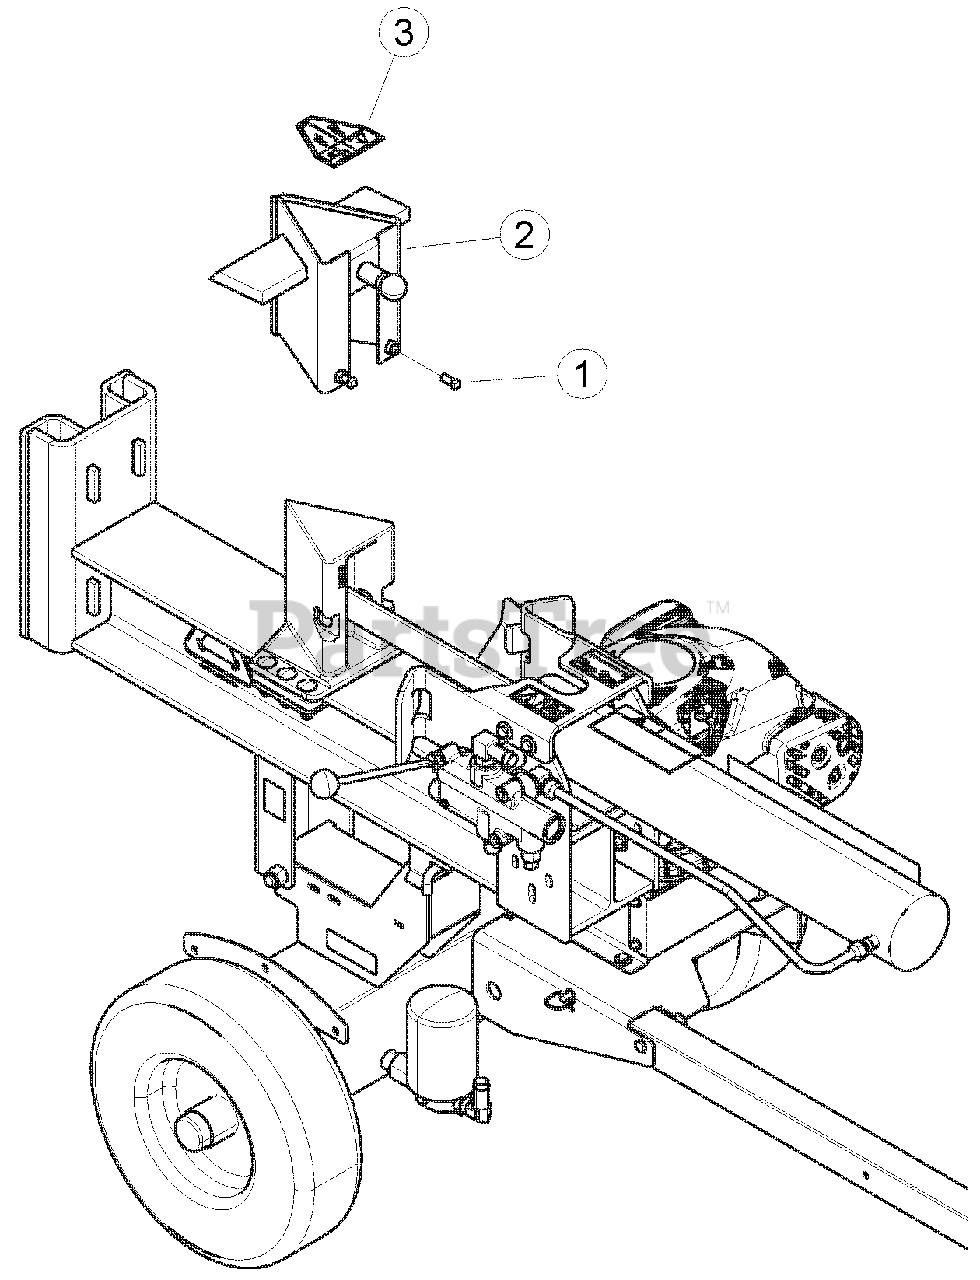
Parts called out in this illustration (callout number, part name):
1	SCREW, 3/8 X 3/4 SQ HD SET ZP
2	ASSEMBLY, 4-WAY WEDGE, SERVICE PART
3	DECAL, WEDGE CAUTION
